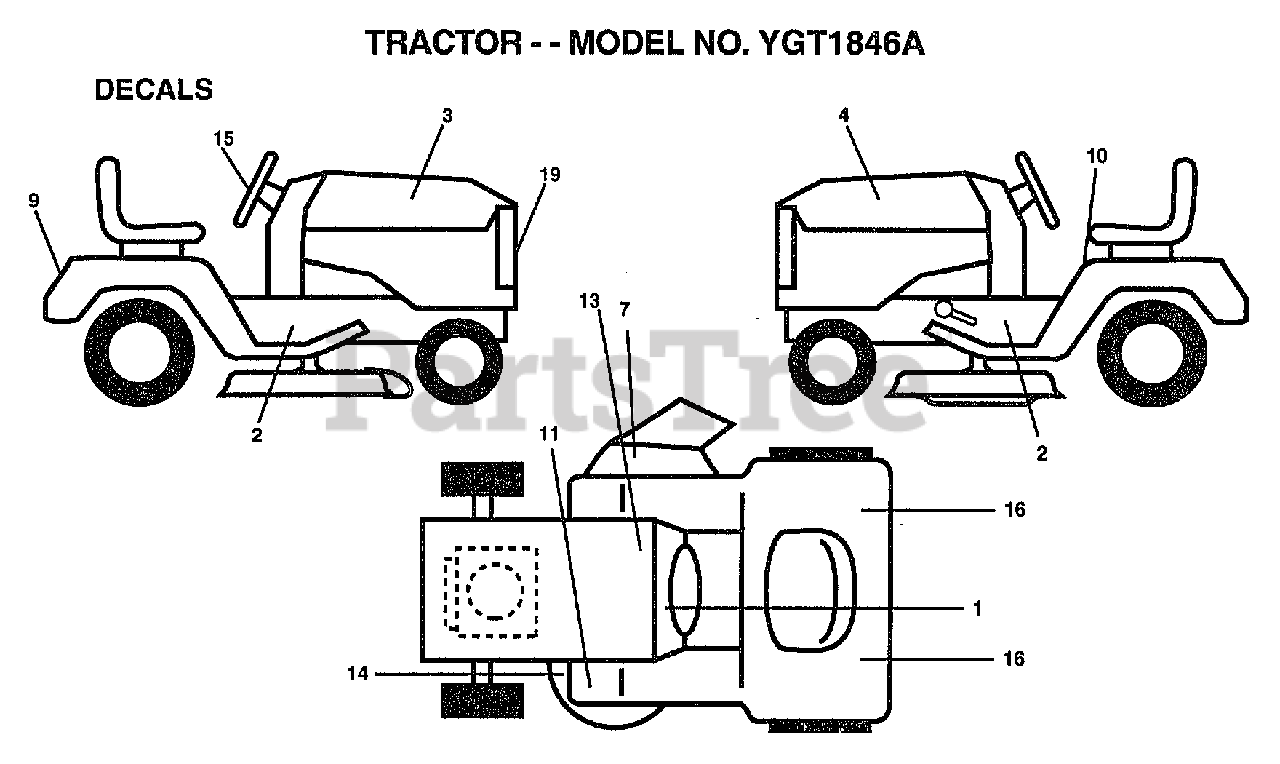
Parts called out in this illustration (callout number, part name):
1	DECAL.INSTR.FRENC
2	"DECAL CHASSIS,46"""
3	"DECAL HOOD,RH,18H"
4	"DECAL-HOOD,LH,18H"
7	"DECAL, WARNING"
9	DECAL FENDER
10	DECAL.CAUT.ENG/FR
11	DECAL T
13	DECAL.BATRY.3-3908
15	DECAL INS STRG WH
16	REFLECTOR-TAIL YT
19	DECAL GRILLE
